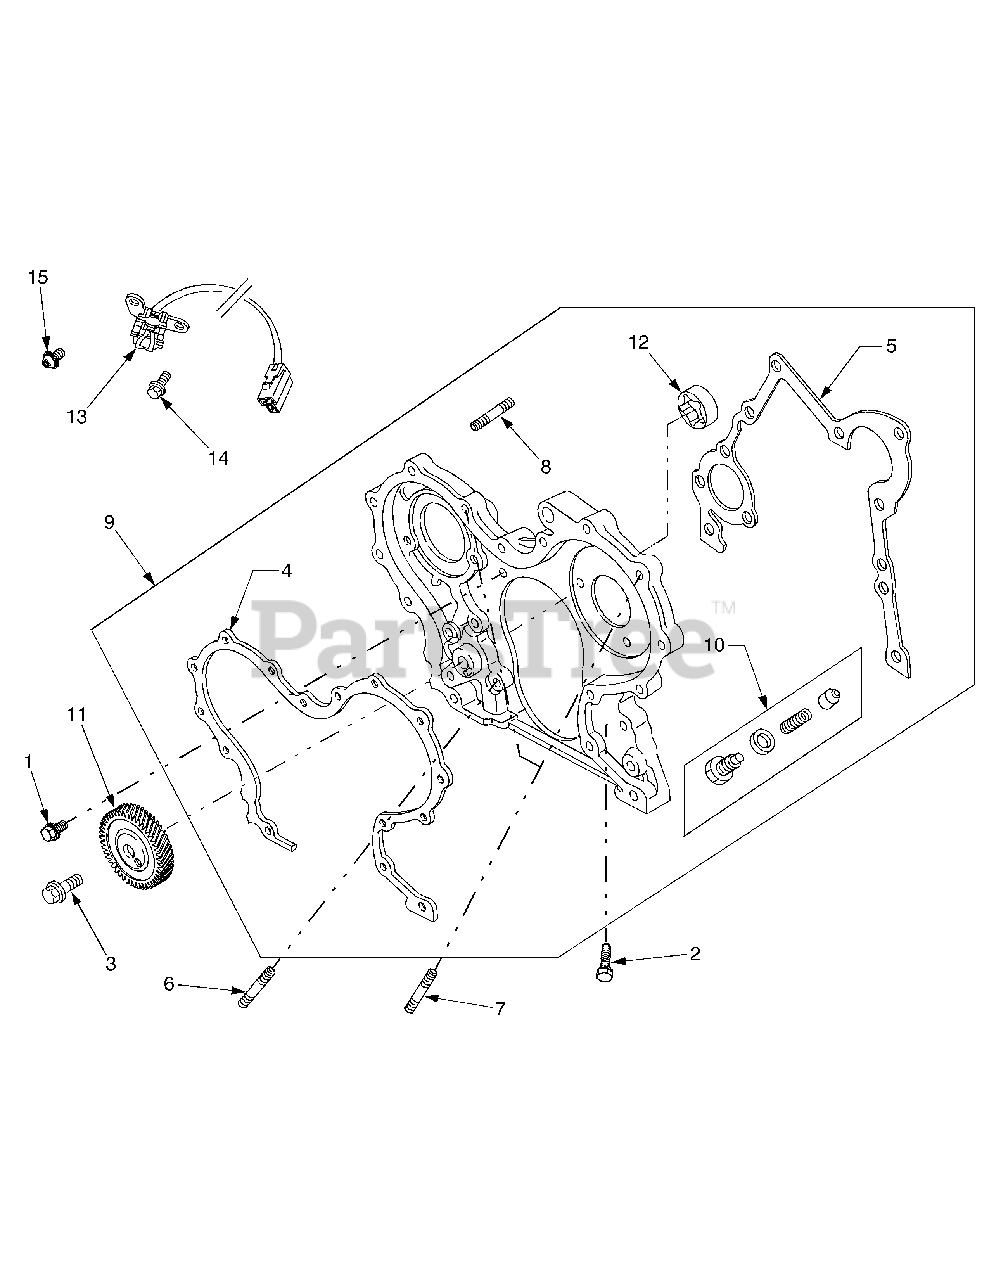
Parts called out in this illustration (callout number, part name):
1	Screw, Hex, 6mm
2	Screw, Hex, 6mm
3	Screw, Hex, 8mm
4	Gasket, Gear Cover
5	Gasket, Gear Cover
6	Stud, Metric
7	Stud, Metric
8	Stud, Metric
9	Housing, Gear
10	Valve, Oil Relief
11	Gear, Oil Pump Drive
12	Pump. Oil - Sold ONLY in Gear Housing (Ref. 9)
13	Trigger - Ignition
14	Screw (Trigger Ignition)
15	Screw (Trigger Ignition)
